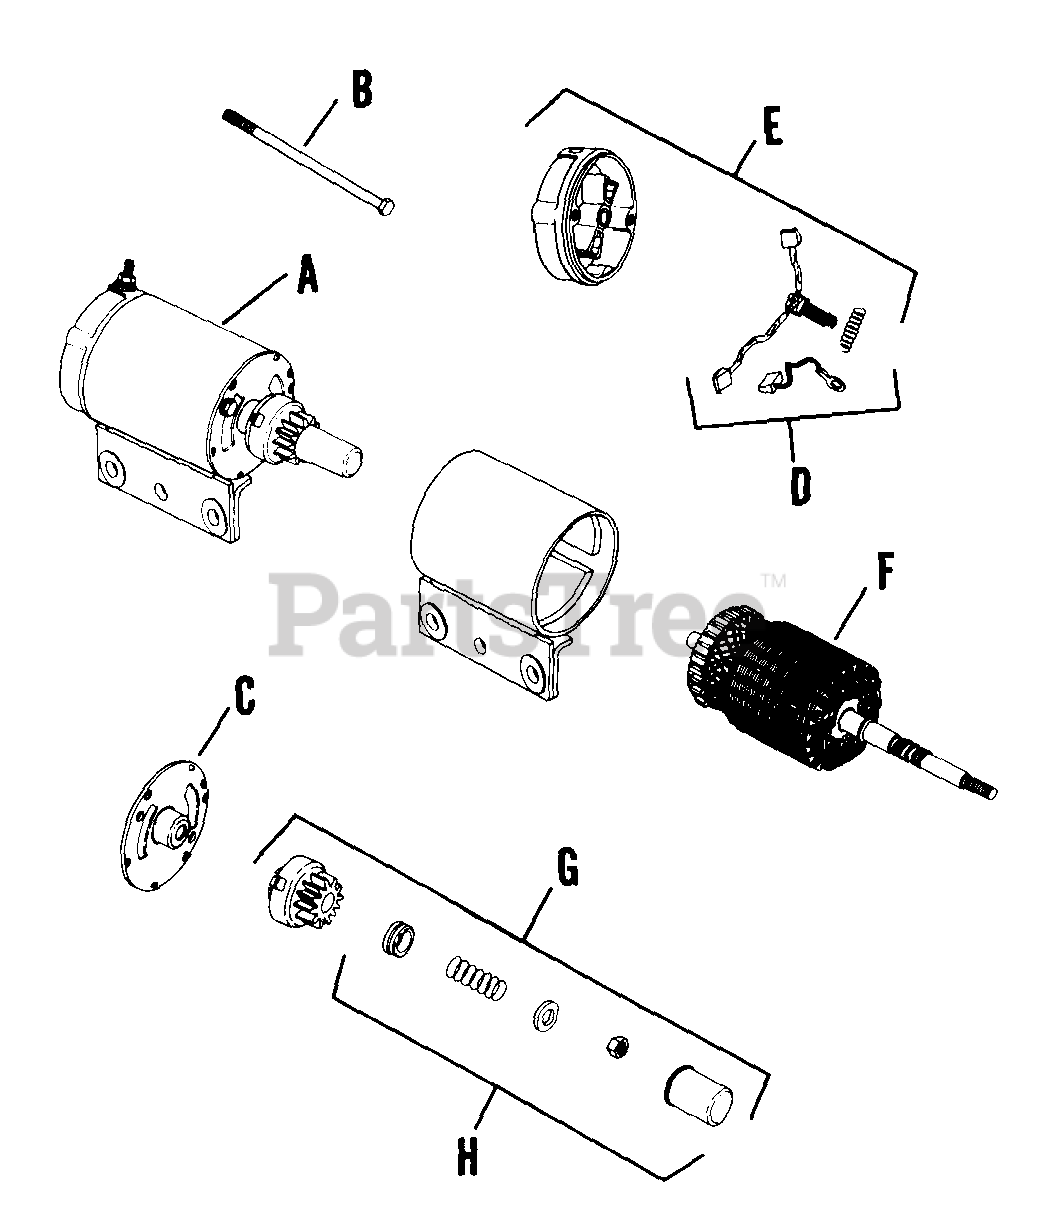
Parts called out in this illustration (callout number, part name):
A	STARTER - USE 45 098 03
C	CAP - USE 45 081 05
D	KIT - USE 52 755 15
E	CAP - DISCONTINUED
F	KIT, ARMATURE - DISCONTINUED
G	STARTER - USE 45 098 09
